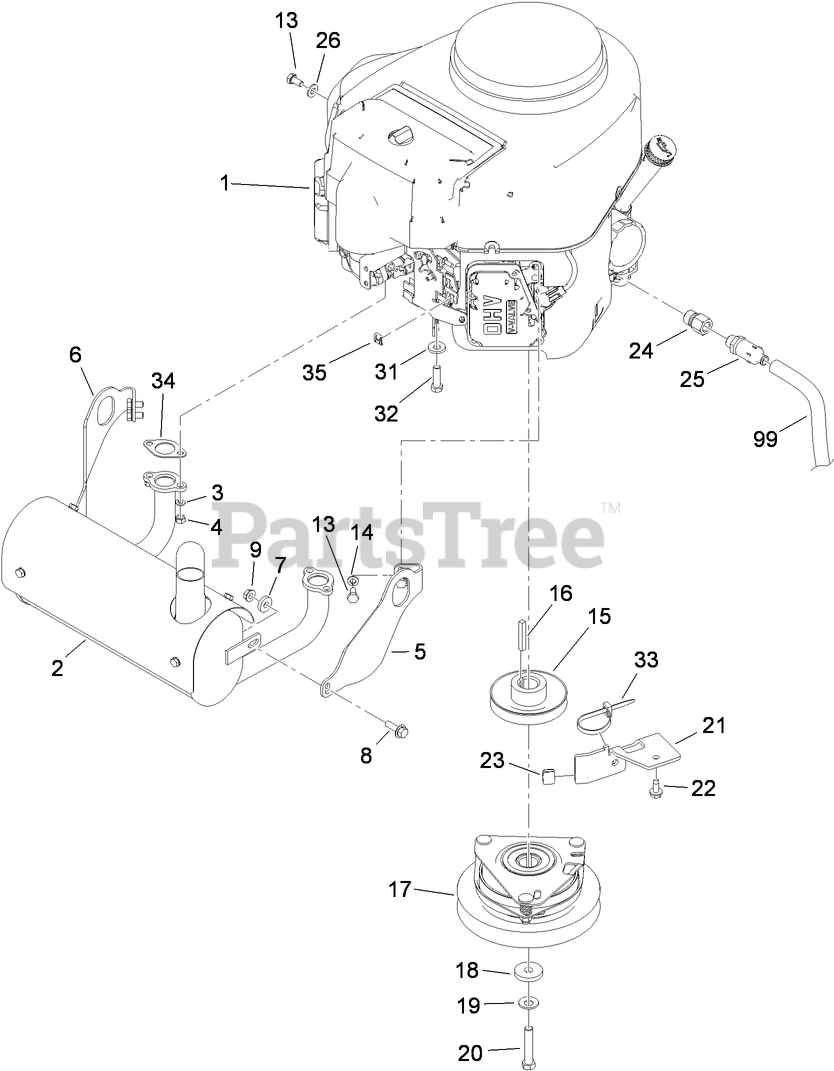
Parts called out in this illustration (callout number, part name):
2	MUFFLER
3	WASHER-LOCK
5	BRACKET-MUFFLER MOUNT, LH
6	BRACKET-MUFFLER MOUNT, RH
7	SPACER
8	SCREW-HHF
9	NUT-HF
13	SCREW-HH
14	WASHER-LOCK
15	PULLEY
16	KEY-SQUARE
17	CLUTCH / BRAKE ASM
18	WASHER
19	WASHER-SPRING
20	SCREW-HH
21	BRACKET-STOP, PTO
22	SCREW-HWHTF
23	BUMPER
24	Adapter
25	VALVE-DRAIN, OIL
26	WASHER-PLAIN
31	WASHER-BELLEVILLE
32	SCREW-HH
33	TIE-CABLE
34	GASKET-EXHAUST
35	CLAMP-CABLE
99	HOSE-DRAIN, OIL
